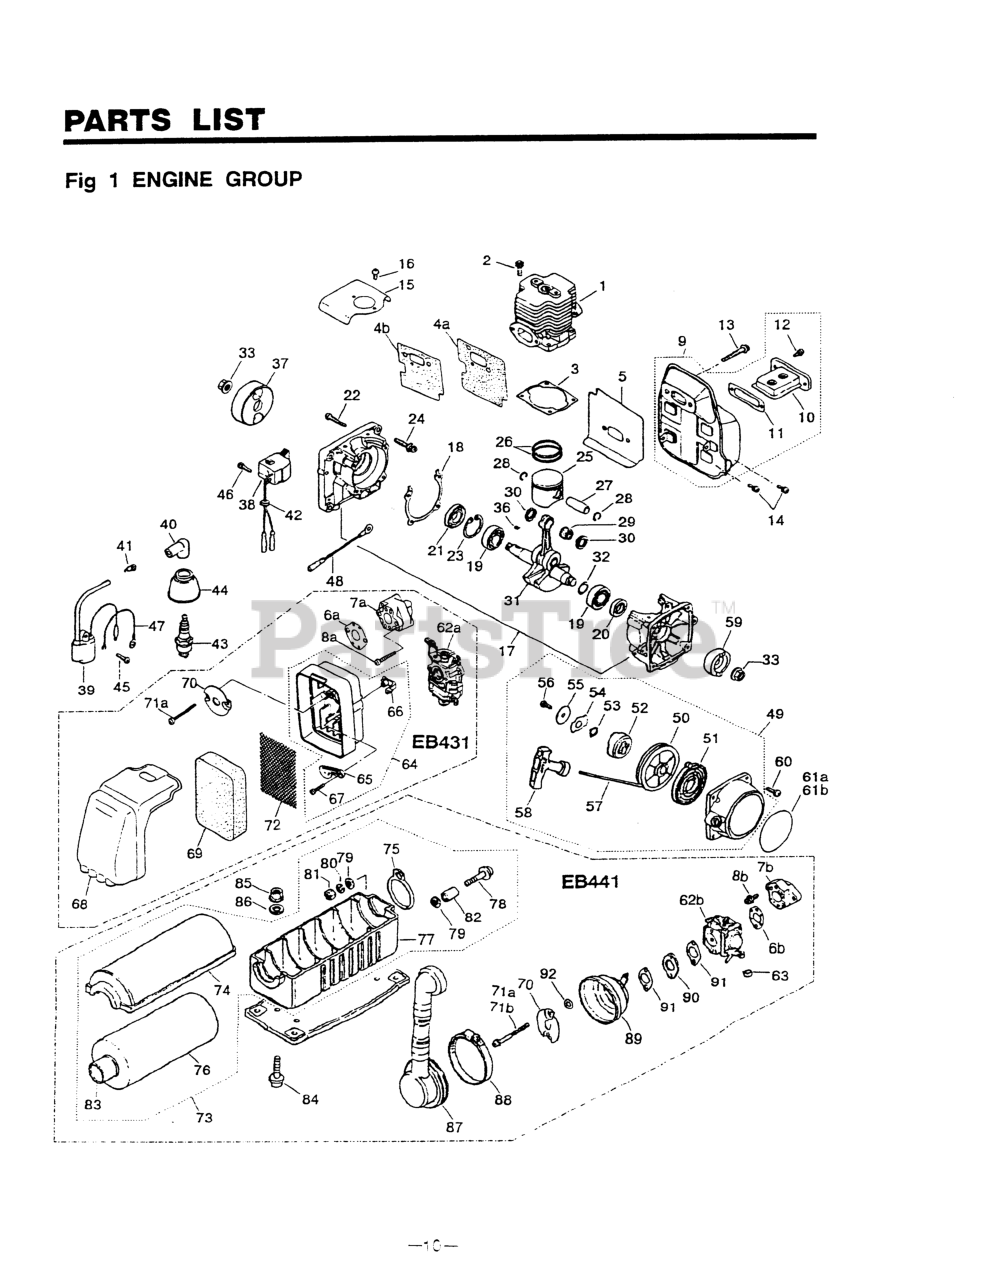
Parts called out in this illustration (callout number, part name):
1	CYLINDER (RPLS -12111)
7B	INSULATOR (RPLS-14112)
9	MUFFLER (RPLS -15101)
10	ARRESTER
12	SCREW, M4 x 10
17	CRANKCASE
20	SEAL, OIL - STARTER SIDE
22	BOLT, M5 X 30
23	RING, SNAP, M35 X 1.5
26	RING, PISTON (RPLS -41210)
27	PIN, PISTON (RPLS. 1490-41316)
28	RING, SNAP
29	BEARING
30	WASHER (RPLS 1491-41510)
31	SHAFT (RPLS -42001)
32	SHIM (REPLACES 848-870-G000)
33	NUT, M10
36	KEY
39	COIL, IGNITION
41	SPRING
42	GROMMET
44	CAP (NO LONGER AVAILABLE)
45	SCREW, M4 x 16
46	BOLT, M4 X 16
47	CABLE COMPLETE
51	SPRING (RPLS -75220)
52	DOG
54	RETAINER (RPLS 1861-75161)
55	WASHER
56	SCREW
57	ROPE
58	KNOB
59	PULLEY (RPLS -75210)
60	BOLT, M5 x 20
63	CAP, CABLE END
70	PLATE (REPLACES -82511)
71B	SCREW, M5 X 55
73	CLEANER, AIR
74	COVER, CLEANER
75	BAND
76	ELEMENT
77	CASE, CLEANER
79	WASHER, M5 X .8
80	WASHER, SPRING M4 x 1.3
81	NUT, M5 X 4
82	COLLAR (NLA)
84	SCREW, M5 x 16
85	NUT (B)
86	WASHER, M5 X .8
87	HOSE (RPLS -83300)
88	CLAMP
89	CASE, CLEANER
NI	KIT, GASKET
